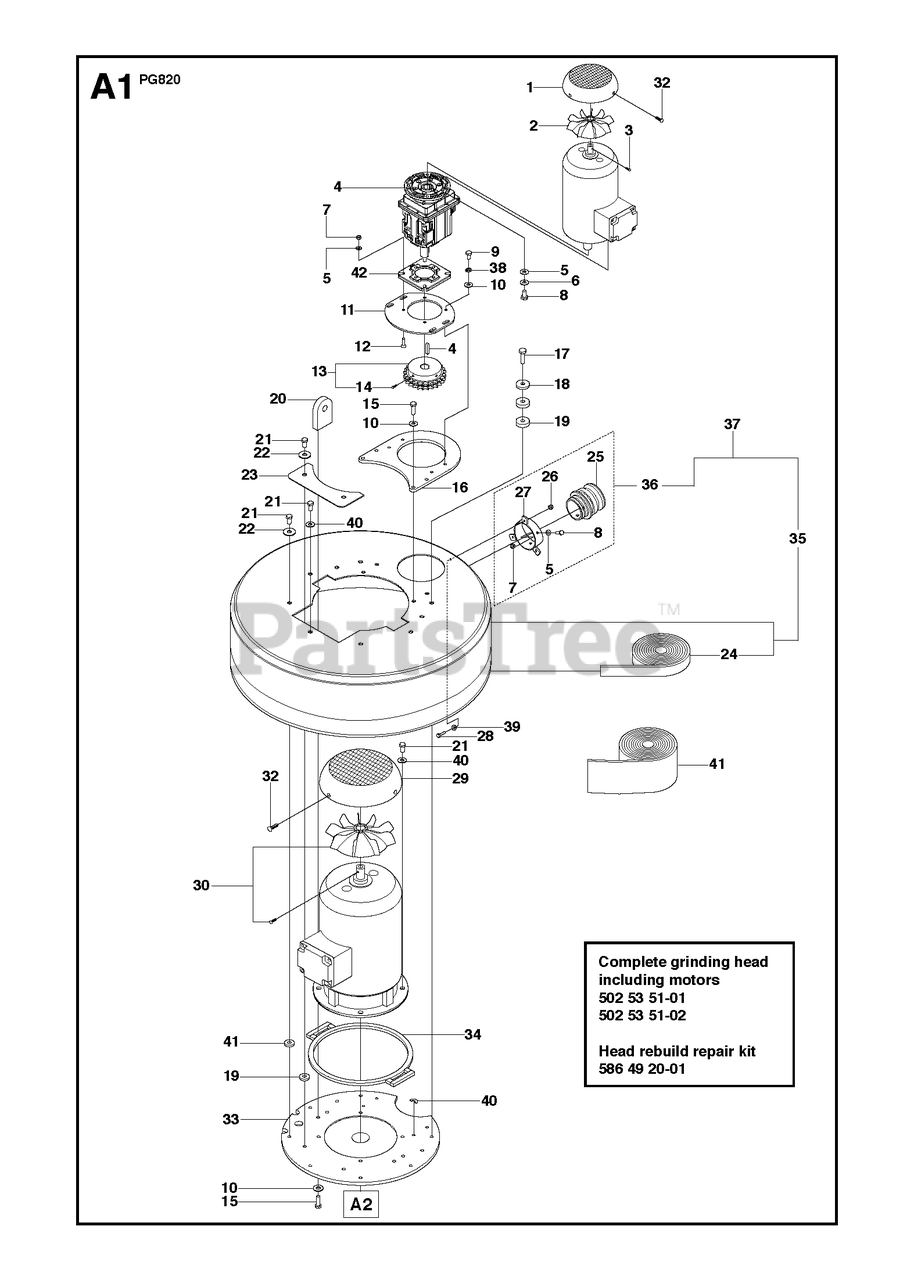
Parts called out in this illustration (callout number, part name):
5	WASHER
6	SPRING WASHER
7	HEXAGON LOCKING NUT
10	WASHER
22	WASHER
26	HEXAGON LOCKING NUT
28	SCREW CRCSFM
